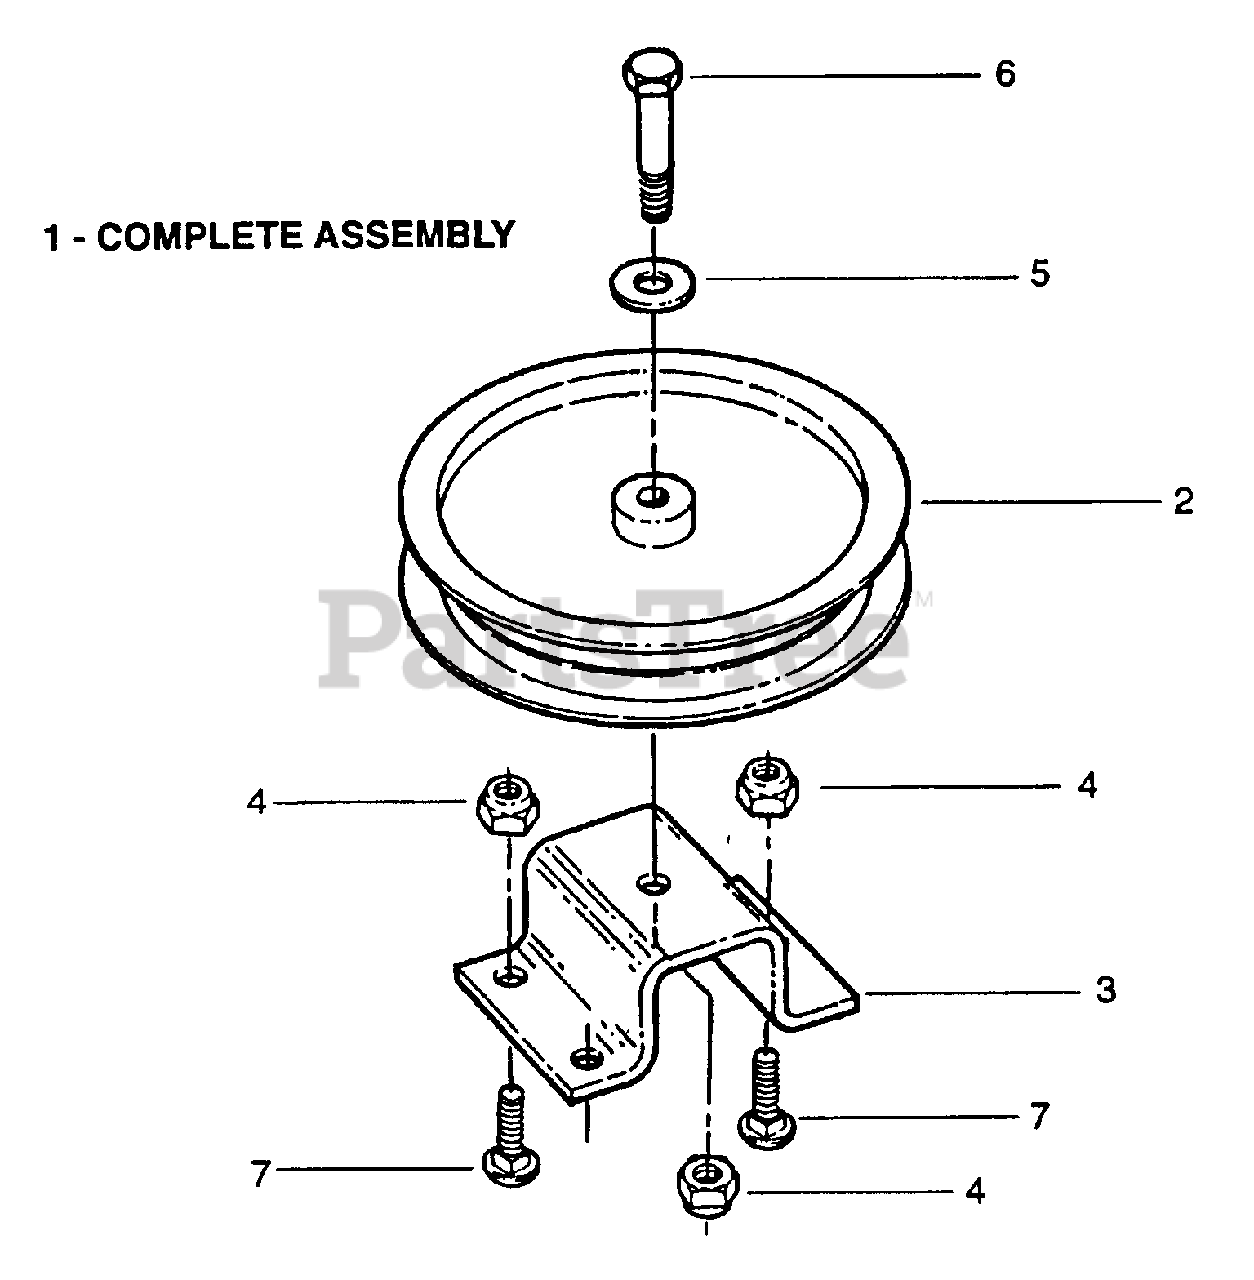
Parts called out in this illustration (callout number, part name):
1	ASSEMBLY, Fixed Idler Group
2	PULLEY, 5-1/2" O.D. Idler
3	STAND, Fixed Idler
4	NUT, 3/8-16 HEX NYLON LOCK
5	WASHER, 3/8" USS
6	BOLT, 3/8-16 X 2, GD5, CZ
7	BOLT, 3/8 - 16 x 1" Rounded Head Square Neck
